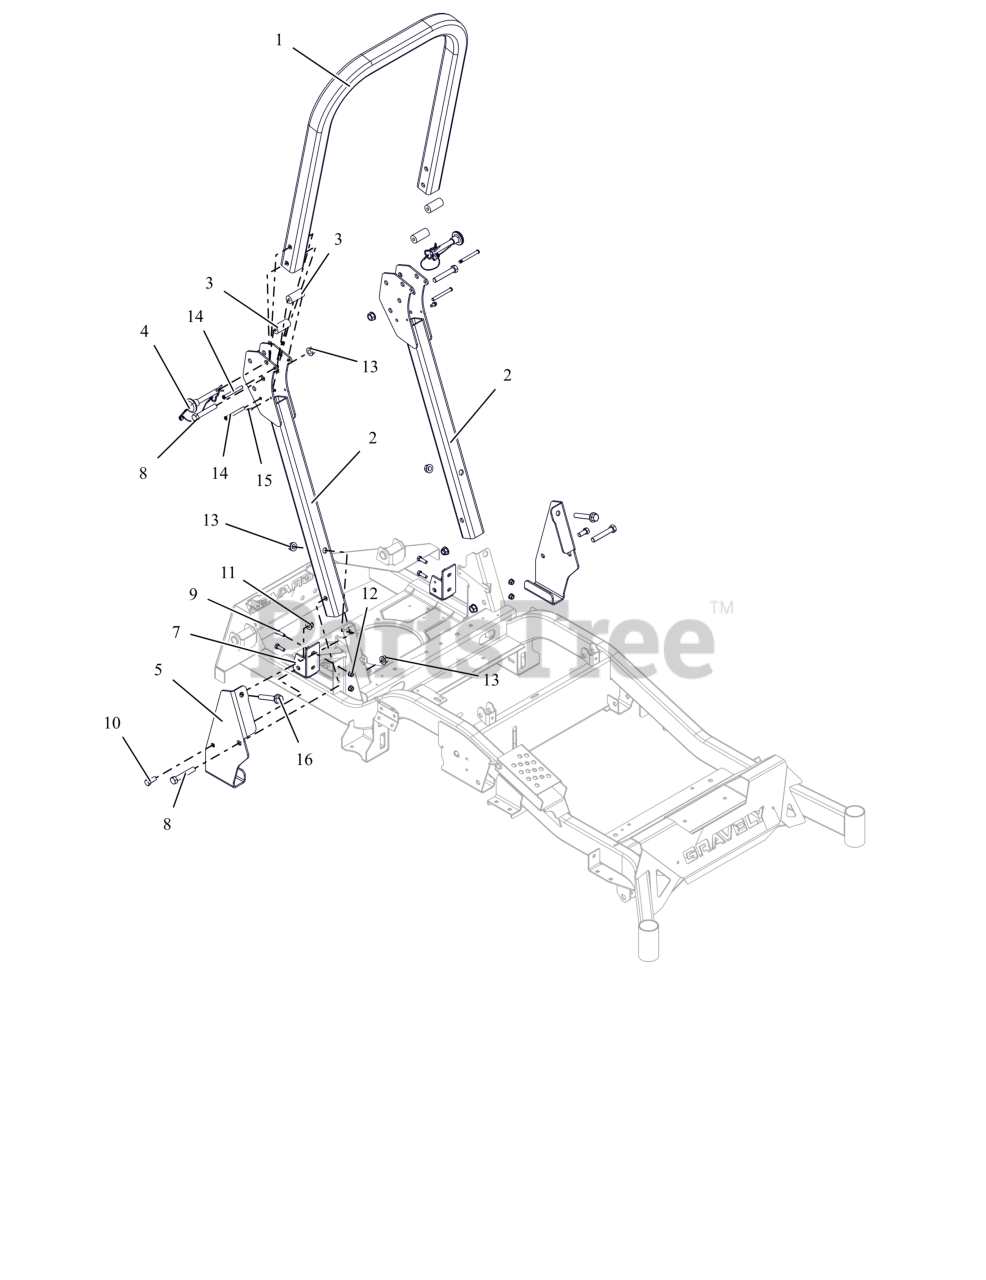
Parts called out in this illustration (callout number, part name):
1	HOOP, PT Z & ZX ROPS
2	ROPS,PROTURN Z REPLACEMENT-TALL
3	BUMPER, ROPS ANTI-VIBRATION
4	PIN, ROPS W/LANYARD
5	BRKT, ROPS SUPPORT - RH
6	BRKT, ROPS SUPPORT -LH
7	BRKT, ROPS SUPPORT
8	BLT, HEX .50-13X3.00 G5 ZCC
9	BLT, HEX .31-18X1.00 G8 ZCC
10	BLT, HEX 0.4375-14X1 GR5 ZCC
11	NUT,NYL-FLG .44-14 GF ZCC
12	NUT,LK-CTR-FLG .31-18 GF ZCC
13	NUT-LK-CTR-FLG .500-13 GG ZCC
14	PIN, SLIC .312 X 2.570
15	SCR-TAP .25-20X.50 HWH ZCC
16	BLT- HEX-FLG .50-13X3.00 G5 ZC
